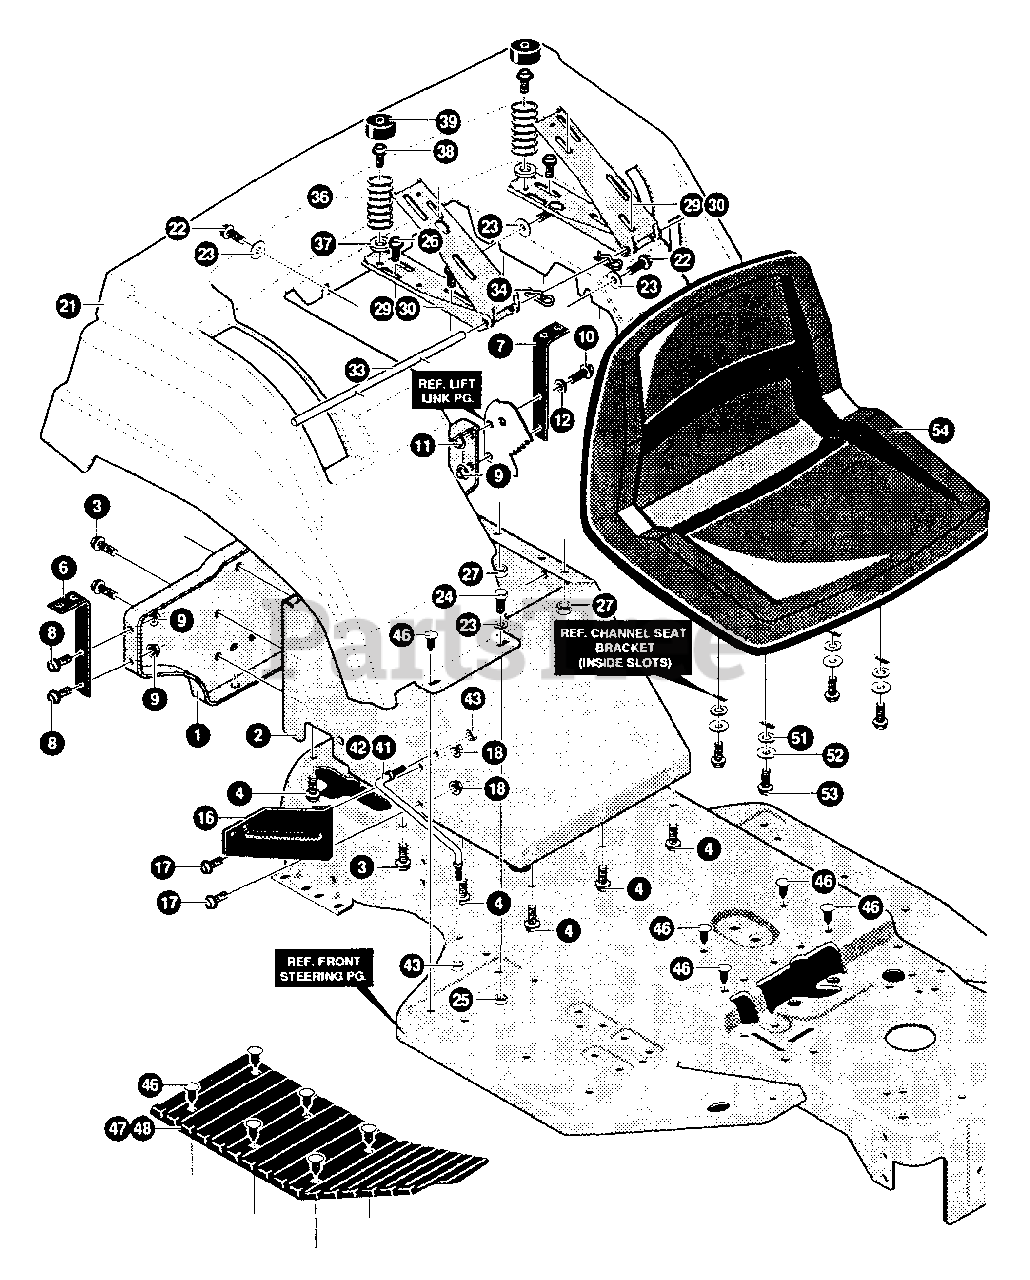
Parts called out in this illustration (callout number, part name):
1	SEAT SUPPORT ELECTRIC LIFT
2	SUPT FENDER & SEAT ELECT/LIFT
3	SCREW, 5/16-18 X .75 WAHHTAP
4	SCREW, 5/16-18 X .50 WAHHTAP
6	SUPPORT FENDER RIGHT
7	SUPPORT FENDER LEFT
8	SCREW, 5/16-18 X .75WDFLLK
9	NUT, 5/16-18 HXWDFLLK
10	SCREW, 1/4-20 X .75 HHC
11	NUT, 1/4-20 WDFLWHIZ-LK
12	WASHER, FLAT .250 X .56 X .049
16	SUPPORT, SHIFT PLATE
17	SCREW, 5/16-18 X .75WDFLLK
18	NUT, 5/16-18 HXWDFLLK
21	FENDER, EURO F-10 GT MOLD GREY
22	SCREW, 1/4-20 X .75 WAHHTAP
23	WASHER, FLAT .281 X 1.00 X .063PL
24	SCREW, 1/4-20 X .75 HHC
25	NUT, 1/4-20 REGHEXCTRLK
26	SCREW, 5/16-18 HXWDFLLK
27	NUT 5/16-18 REGHEXCTRLK
29	CHANNEL SEAT RH
30	CHANNEL SEAT LH
33	ROD SEAT SUPPORT BRZN
34	PIN, HAIR .072 DIA X 1.13LG
36	SPRING, SEAT 1.50OD X 2.25LG
37	WASHER, FLAT .344 X .69 X .065
38	SCREW, 5/16-18 X .75 WAHHTAP
39	COVER, SEAT SPRING 1.5IDX1.0LG
41	SUPPORT, FOOTREST STIFNR RH ZPL
42	SUPPORT, FOOTREST STIFNR LH ZPL
43	NUT 5/16-18 REGHEXCTRLK
46	FASTENER, RATCHET BLACK
47	FOOT PAD, ASSYRH ERO W/ADH
48	FOOT PAD, ASSYLH ERO W/ADH
51	WASHER, FLAT .344 X .69 X .065
52	WASHER, HVSPTLK .328 X .60 X .09
53	SCREW, 5/16-18 X .75 HHC
54	SEAT, W/SW HOLE
